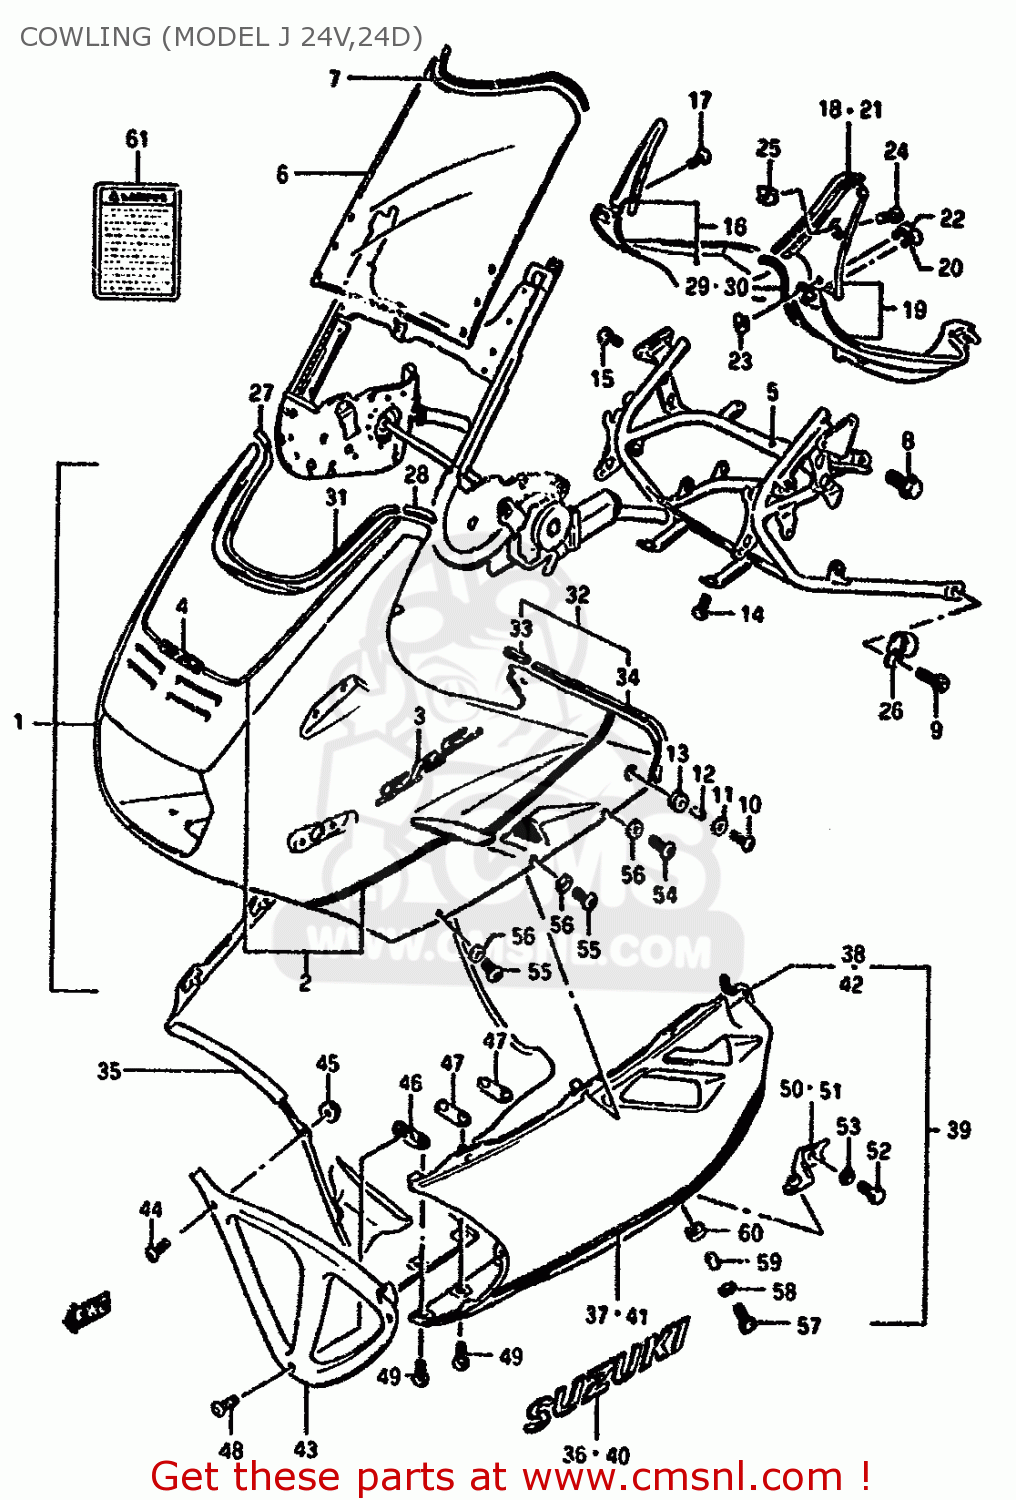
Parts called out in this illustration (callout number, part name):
1	COWLING ASSEMBLY,BODY
2	TAPE SET,COWLING
3	EMBLEM
4	EMBLEM
5	BRACE,COWLING
6	WINDSCREEN
7	MOLDING
8	BOLT(10X12)
9	BOLT
10	SCREW(6X20)
11	WASHER(6.5X18X1)
12	SPACER
13	CUSHION
14	SCREW(6X16)
15	SCREW 6X12
16	PANEL ASSY,R
17	SCREW
18	MOLDING,COWL.
19	PANEL ASSEMBLY,LEFT
20	SCREW
21	MOLDING,COWL.
22	SCREW, FRONT & REAR
23	NUT
24	SCREW
25	NUT
26	CLAMP
27	CAP,PANEL & COWLING,R
28	CAP,PANEL & COWLING,L
29	MOLDING,COWLING PANEL,R
30	MOLDING,COWLING PANEL
31	MOULDING
32	MOLDING,COWLING BODY SIDE
33	COVER,MOLDING END
34	MOLDING,COWLING BODY SIDE
35	COVER,COWL.RH
36	EMBLEM
37	TAPE,COWLING,RIGHT
38	MOLDING,COWLING,LOWER
39	COVER ASSY,COW
40	EMBLEM
41	TAPE,COWLING
42	MOLDING,COWLING,LOWER
43	COVER,COWLING,LOWER,FRONT
44	SCREW(5X14)
45	NUT
46	BRACE,COWLING LWR COVER
47	BRACE,COWLING LWR COVER RR
48	SCREW(6X12)
49	SCREW(6X16)
50	BRACE,COWLING LWR,R
51	BRACE,COWLING LWR,L
52	BOLT 8X12
53	LOCK WASHER
54	SCREW(6X20)
55	SCREW(6X16)
56	WASHER
57	SCREW(6X20)
58	WASHER(6.5X18X1)
59	SPACER(6.4X9.2X12)
60	CUSHION
61	LABEL (WARNING SCREEN)
